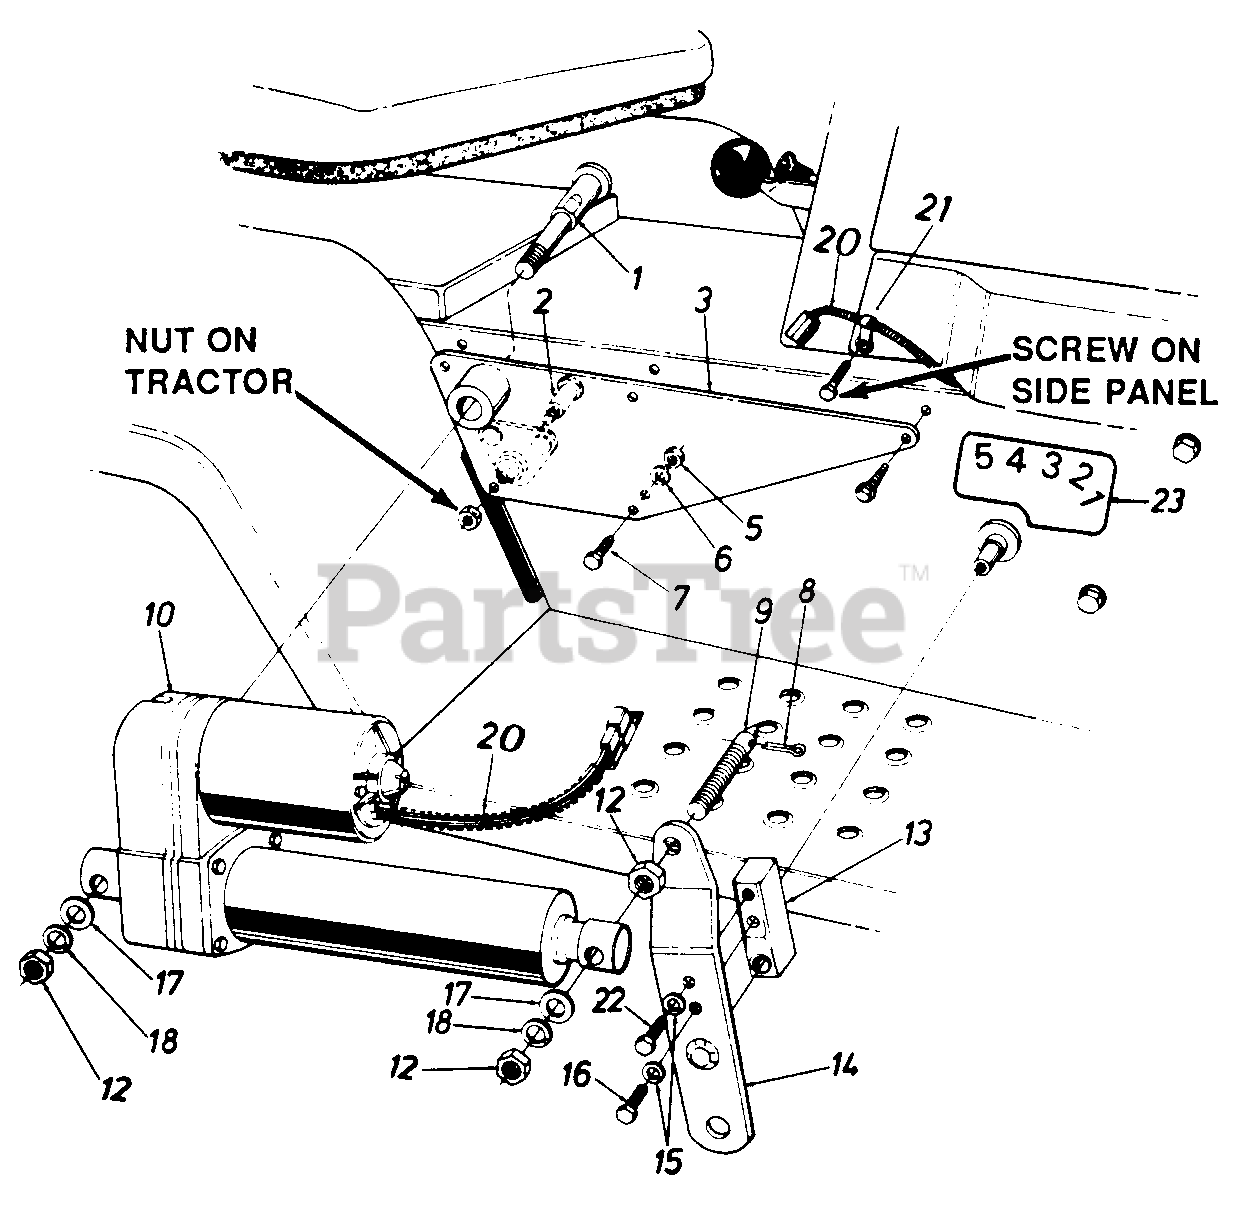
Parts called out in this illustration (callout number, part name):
1	Pivot Pin
2	Shld. Bolt .626 Dia. x .96
6	L-Wash. 1/4 I.D.
7	Hex Bolt 1/4-28 x .75Lg. (Grade 5)
8	Cotter Pin
9	Indicator & Mtg. Pin
10	Electric Actuator
12	Hex Jam Nut 1/2-13 Thd.
13	Lift Shaft Drive
16	Hex Bolt 5/16-24 x 1.0" Lg. (Grade 5)
17	Fl-Wash. .53" I.D. x .930.D.
18	L-Wash. 1/2" I.D.
20	Plastic Harness
21	Clamp
22	Hex Bolt 5/16-18 x 1 Lg. (Grade 5)
23	Label
